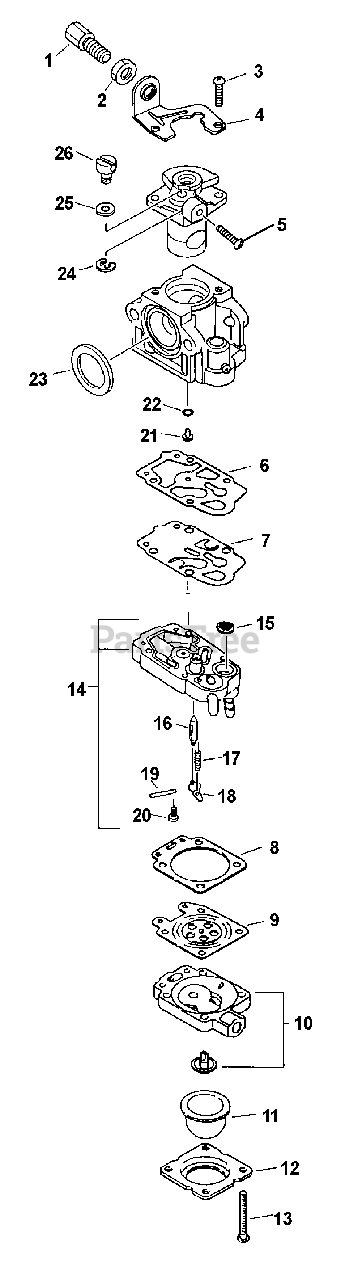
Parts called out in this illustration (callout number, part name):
1	ADJUSTER, THROTTLE CABLE
2	NUT, ADJUSTER LOCK M7
4	BRACKET, THROTTLE CABLE
8	GASKET, METERING
9	DIAPHRAGM, METERING
10	BODY ASSY, PURGE
11	BULB, PURGE
12	RETAINER, PURGE BULB
14	BODY ASSY, PUMP
15	STRAINER
16	VALVE, INLET NEEDLE
17	SPRING, METERING LEVER
18	LEVER, METERING
19	PIN, METERING LEVER
21	JET, MAIN
23	SEAL
